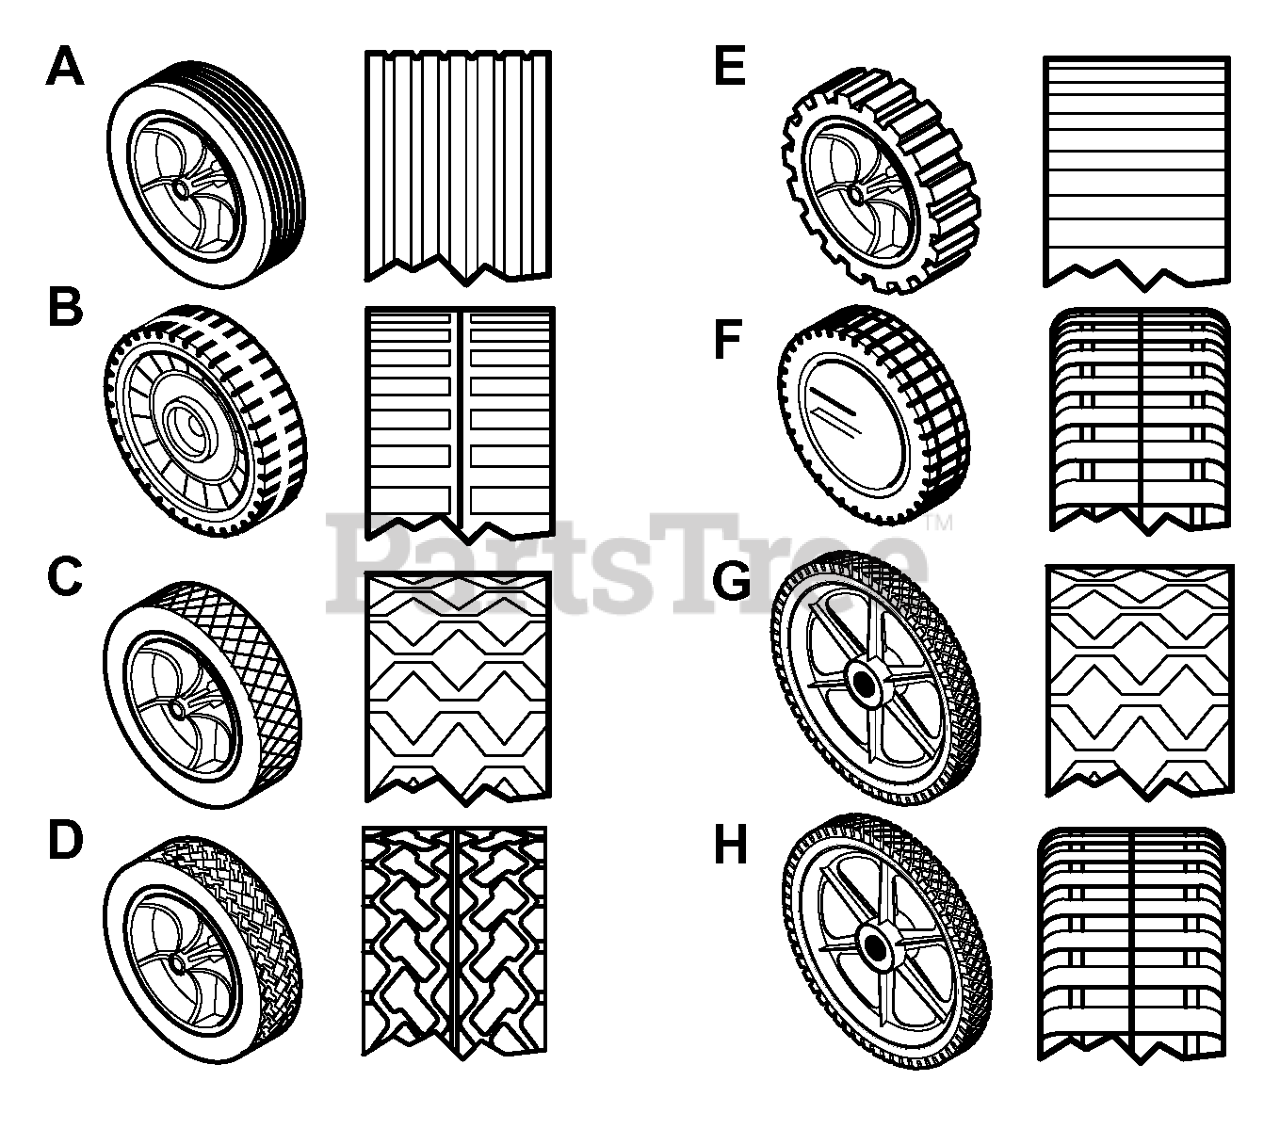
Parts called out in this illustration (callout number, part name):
A	WHEEL & TIRE ASSEMBLY, Light Gray, 8"
A	8-inch Plastic, Dark Gray
A	8-inch Metal, White
B	7-inch Plastic, White
B	7-inch Plastic, Light Gray
B	7-inch Plastic, Dark Gray
C	6-inch Plastic, White
C	7-inch Plastic, White
C	7-inch Plastic, Light Gray
C	7-inch Plastic, Dark Gray
C	8-inch Plastic, White
C	8-inch Plastic, Light Gray
C	8-inch Plastic, Dark Gray
C	8-inch Metal, White
D	7-inch Plastic, White
D	WHEEL & TIRE ASSEMBLY, White, 8"
D	8-inch Plastic, Light Gray
D	8-inch Plastic, Dark Gray
E	WHEEL & TIRE ASSEMBLY, White, 8"
E	8-inch Plastic, Dark Gray
E	8-inch Metal, White
F	WHEEL & TIRE ASSEMBLY, White, 8"
F	8-inch Plastic, Light Gray
F	8-inch Plastic, Dark Gray
F	8-inch Ball Bearing, Light Gray
F	8-inch Ball Bearing, Dark Gray
G	14-inch, White
G	14-inch, Light Gray
G	14-inch, Dark Gray
G	WHEEL & TIRE ASSEMBLY, White, 14"
G	14-in, Ball Bearing, Light Gray
G	14-in, Ball Bearing, Dark Gray
H	14-inch, White
H	14-inch, Light Gray
H	14-inch, Dark Gray
H	WHEEL & TIRE ASSEMBLY, Ball Bearing, 14"
H	14-in, Ball Bearing, Light Gray
H	14-in, Ball Bearing, Dark Gray
